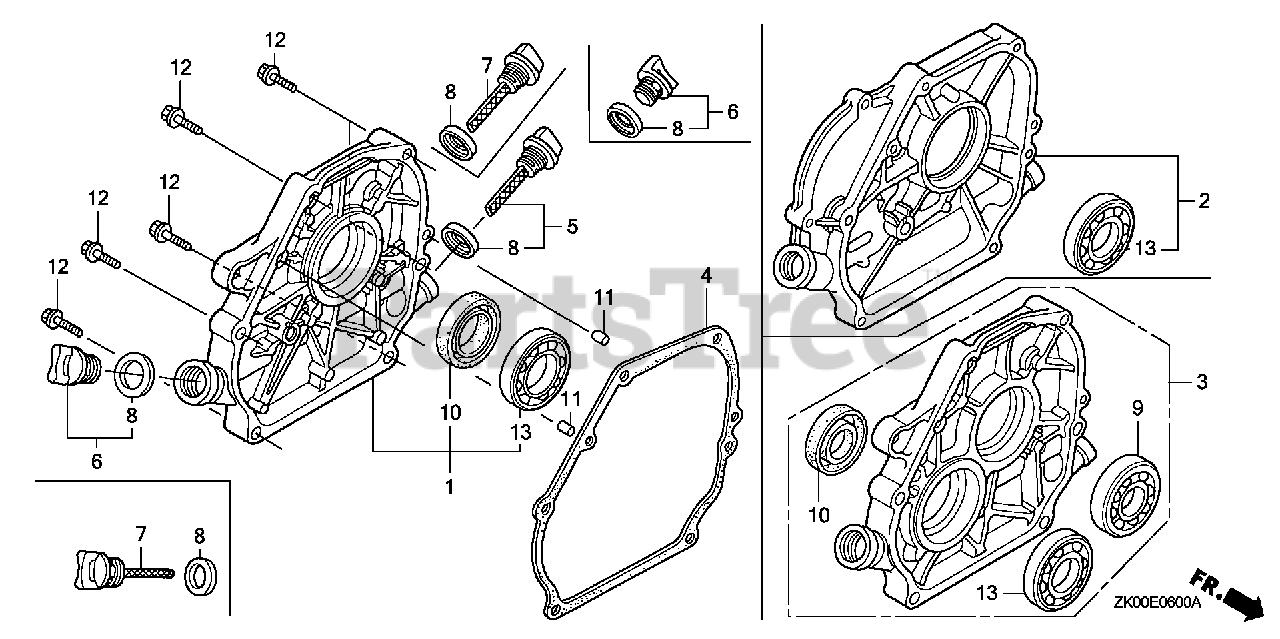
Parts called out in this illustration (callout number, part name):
1	COVER ASSY., CRANKCASE
4	GASKET, CASE COVER
5	CAP ASSY., OIL FILLER (GRAY)
6	CAP ASSY., OIL FILLER
8	GASKET, OIL FILLER CAP
10	OIL SEAL (25X41X6) (NOK)
11	PIN, DOWEL (8X14)
12	BOLT, FLANGE (8X32)
13	BEARING, RADIAL BALL (6205)
